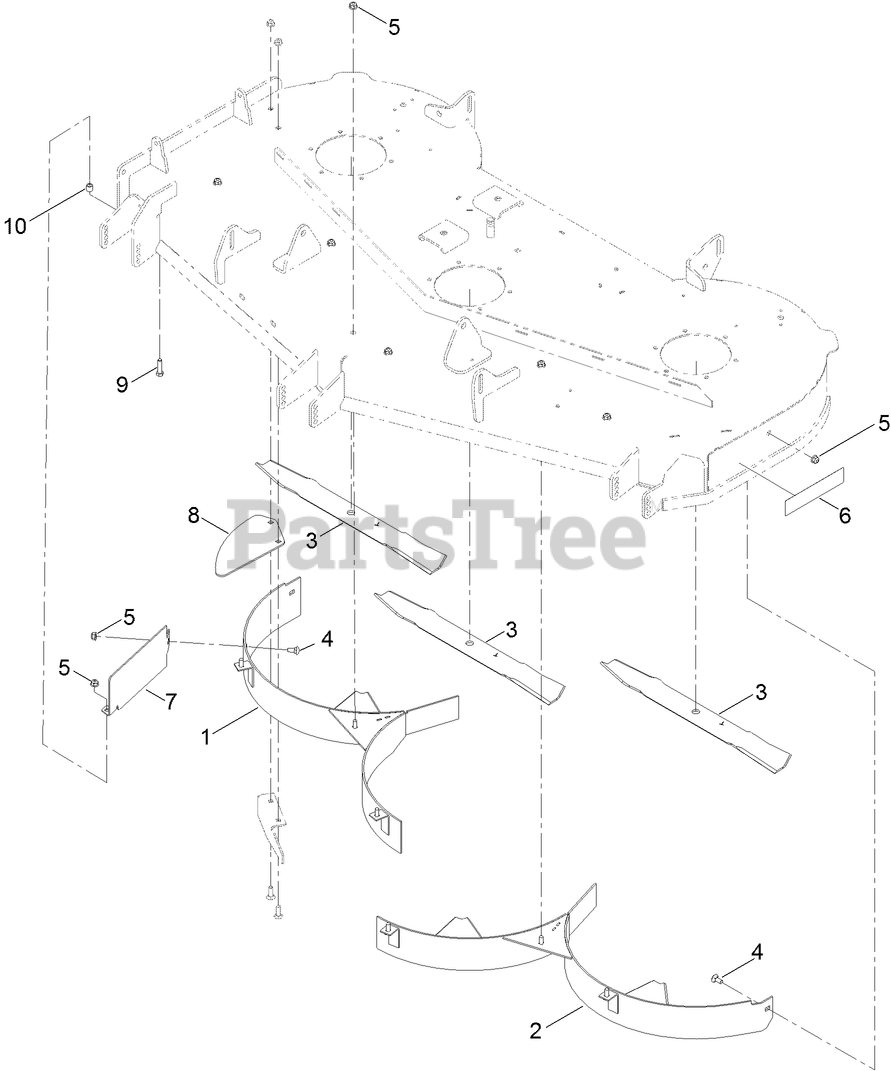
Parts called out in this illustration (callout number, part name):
1	BAFFLE-RH
2	BAFFLE-LH
3	BLADE-MULCH, 20.50 INCH
4	BOLT-CARR
5	NUT-HF, NI
6	DECAL-RECYCLER, 60 INCH
7	GUARD-BAFFLE
8	PLATE-FILLER
9	SCREW-HH
10	SPACER
